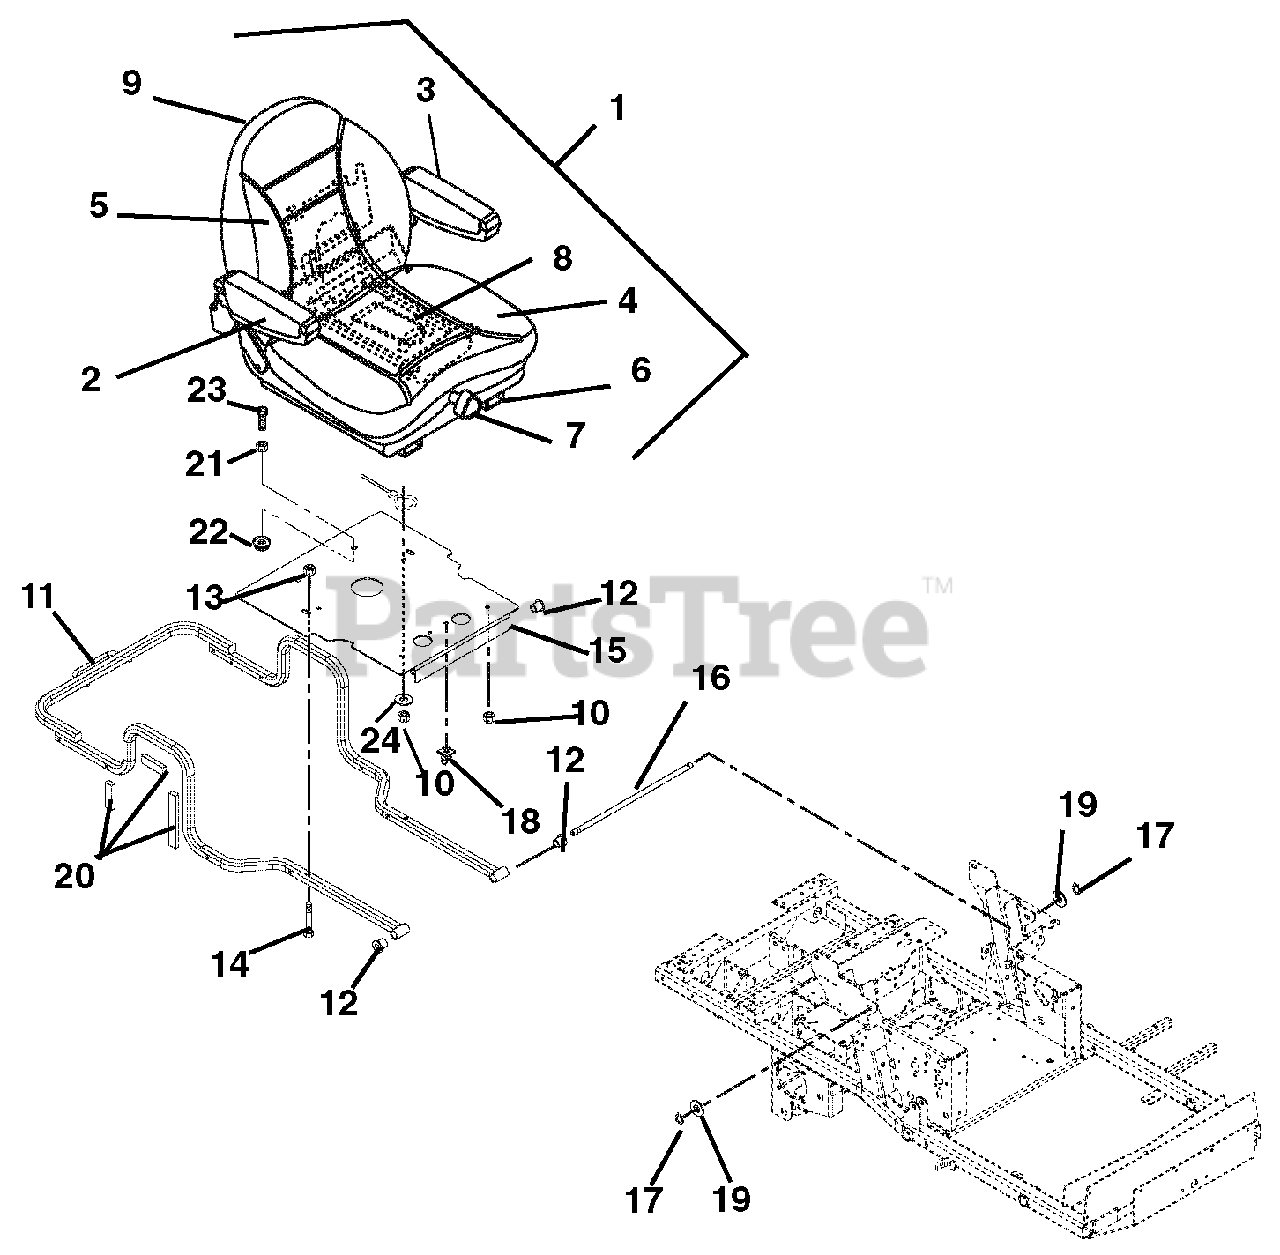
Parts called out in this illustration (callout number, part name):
1	SEAT-SUSP-LT GRY-SEAT BLT BUSH
2	KIT-RH ARMREST ASSEMBLY REPLAC
3	KIT-LH ARMREST ASSEMBLY REPLAC
4	KIT-SEAT CUSHION-LIGHT GRAY
5	KIT-BACK CUSHION-LIGHT GRAY
6	KIT-SEAT SLIDE
7	KIT-SEAT KNOB
8	KIT-SPRING AND SADDLE
9	KIT-SEAT BACK PANEL
10	@NUT-LK-TOP-FLG .31-18 YWZC
11	WMT, HOOD FRAME
12	BSHG-FLG .515X.750X.745X1.00NY
13	@NUT-LK-TOP-FLG .38-16 YWZC
14	BLT, .38-16X1.50 RIB NECK YWZC
15	WMT, SEAT PIVOT MOUNT
16	ROD - SEAT FRAME PIVOT
17	RG-RTNG-EXT .500X.050 (SNAP)
18	CLIP-.38
19	@WSHR-FL-STL.531X1.06X.095YWZC
20	VHB TAPE 4941F
21	@NUT-HEX .50-13 YWZC
22	@NUT-LK-TOP-FLG .50-13 YWZC
23	@BLT-HEX .50-13X1.50 GR5 YWZC
24	WSHR-FL-STL .344X1.125X.135
